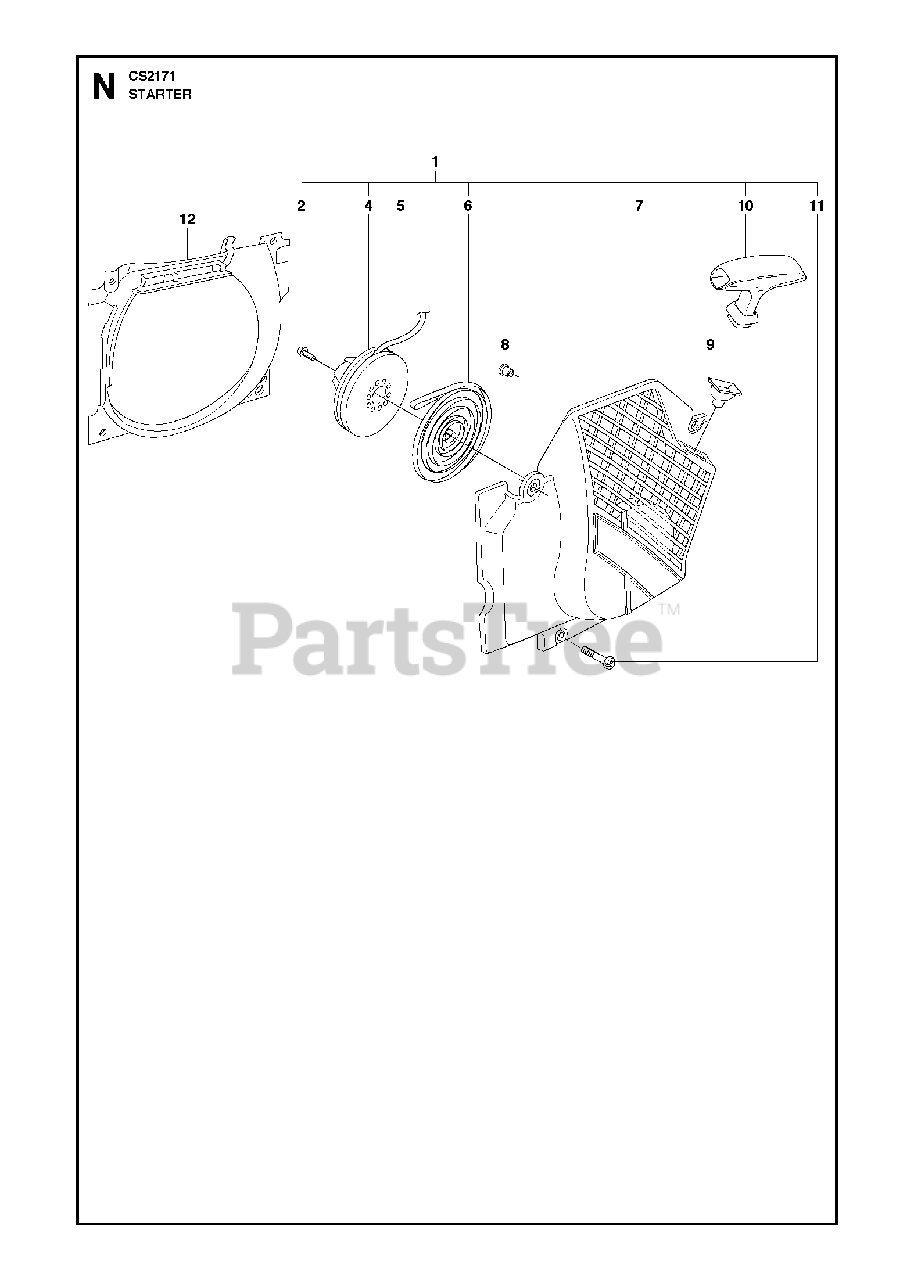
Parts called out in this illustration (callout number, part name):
1	STARTER ASSY
2	SCREW
4	STARTER PULLEY
5	STARTER CORD
6	SPRING
7	STARTER HOUSING
9	SLEEVE
10	STARTER HANDLE
11	SCREW
12	AIR CONDUCTOR
